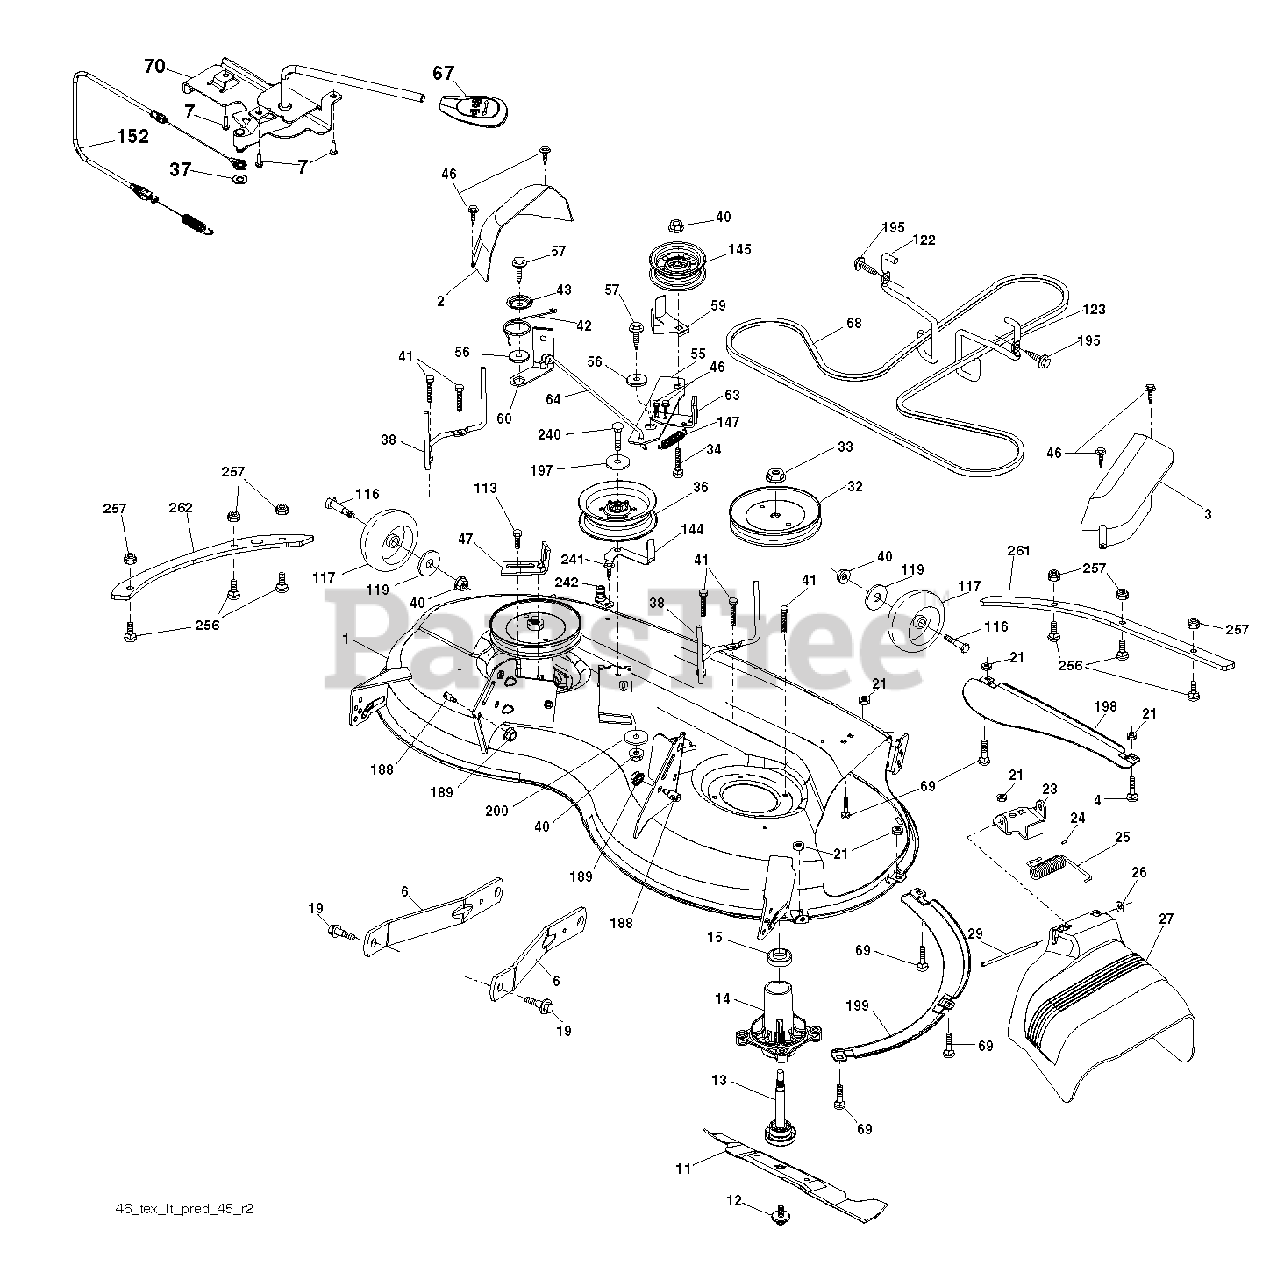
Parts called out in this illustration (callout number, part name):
1	KIT.SVC.WELDMNT.46"405050X421
2	COVER.MANDREL.LH.46"
3	COVER.MANDREL.RH.46"
4	BOLT
6	ARM.SUSPENSION.MOWER.R
7	SCREW.#10 X 0.750.BOS (2 2)
11	BLADE.MOWER.46".HI.LIFT
12	Screw, 7/16 X 20 X 1"
13	Mandrel Assembly, Non-Greaseable
14	HOUSING.MANDREL.4PT.
15	Extended Mandrel Bearing, Top
19	BOLT.SHOULDER
21	LOCKNUT
23	BRKT.DEFLECTOR.38"2005+
24	CAP-SLEEVE LT
25	SPRING.TORSION.DEFLECT
26	NUT PUSH M
27	SHIELD.DEFLECTOR.MOWER.46"BLAC
29	ROD.HINGE
32	PULLEY.MANDREL.5.438.PD
33	NUT.FLANGE.LOCK.TOP
34	BOLT.3/8-16X1.50
36	PULLEY.IDLER.2006
38	KEEPER.BELT.MANDREL.PULLEY
40	NUT LOCK FLG 3/8-16 UNC
41	Hex Washer Head Bolt, .313-18 X 1.19
42	SPRING.TORSION.BRAKE
43	SRPING.TORSION.RETAINE
46	SCREW.1/4-20X5/8
47	BRKT.CLUTCH.CABLE
55	IDLER.ARM
56	SPACER.RETAINER
57	SCREW 3/8-16X1
59	GUARD, BELT
60	ARM BRAKE MOWER RH 38"
64	LINKAGE BRAKE
67	HANDLE.CLUTCH.CABLE.LT
68	V-BELT
69	BOLT
70	CLUTCH.ASM.MANUAL.YT.PREDATORQ
113	BOLT.5/16HEX.WHS.HD
116	BOLT M
117	WHEEL.GAGE.HALF.SPOKED
119	WASHER
122	KEEPER BELT ENGINE LH
123	KEEPER BELT RH
144	KEEPER.BELT.MOWER
145	PULLEY.IDLER.48"PRIMARY
147	RETURN SPRING
152	CABLE.MECHANICAL.CLUTCH
188	STUD.FASTNER.W/ANTI-ROTATE
189	NUT LOCK HEX FLANGE 5/16-18
195	SCREW, 3/8-16X3/4
197	WASHER
198	BAFFLE CENTER FRONT
199	BAFFLE FRONT RH
200	WASHER.13/32 X 1 X 1/2.11GUARD
240	BOLT-HEX EAK
241	SCREW.TT.#10-32X.5.3/8.FLANGE
242	PORT.WASHOUT
256	RHSNB, 1/4-20 X 1, GR5
257	NUT T
261	Deck Reinforcement Plate, 46 F
262	PLATE.REINF.DECK.46.S
